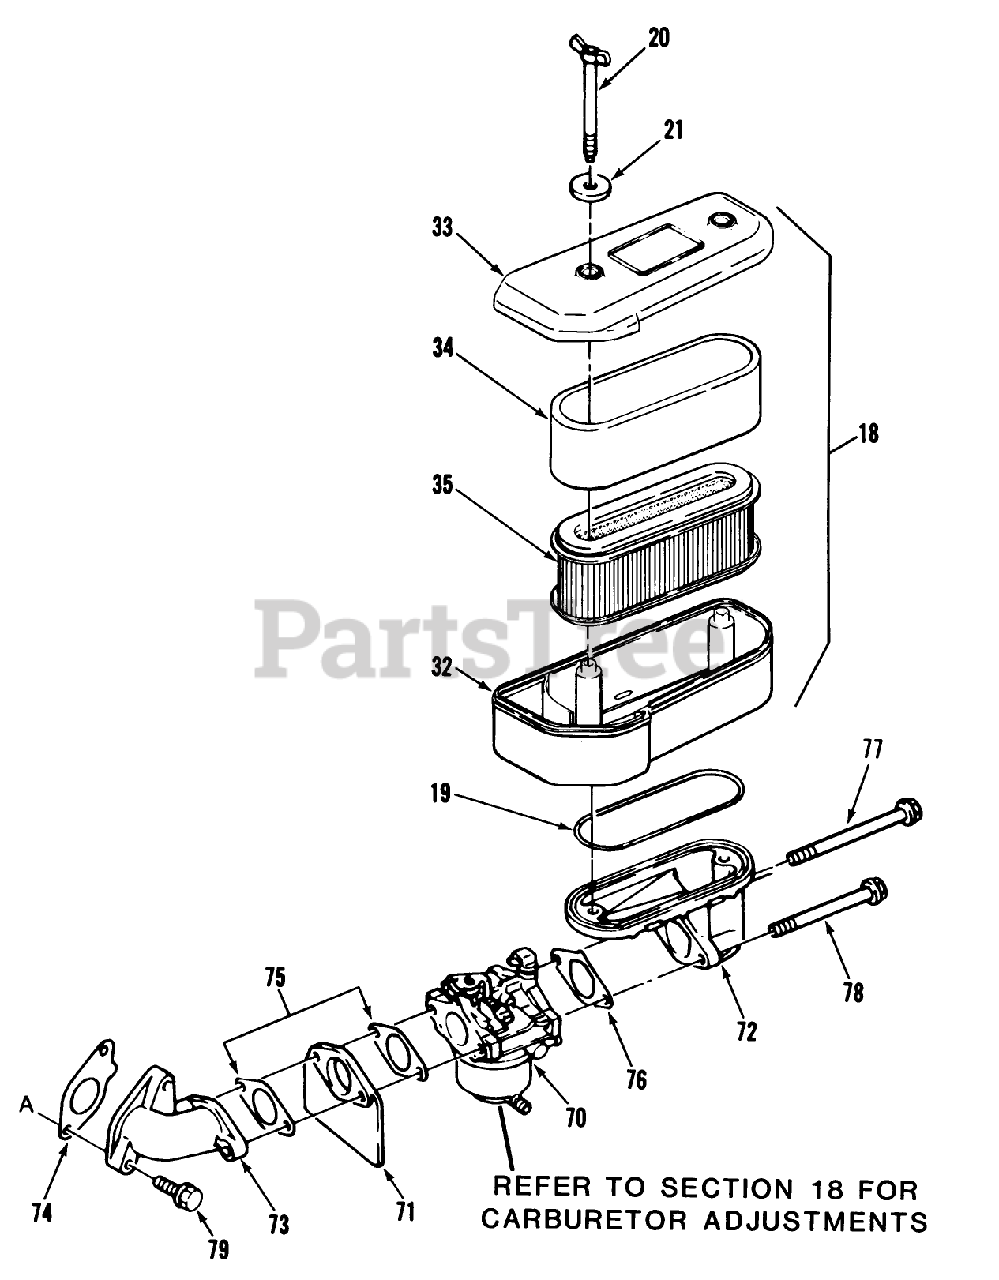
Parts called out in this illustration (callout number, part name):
18	AIR FILTER ASSY
34	ELEMENT-AIR CLEANER
73	MANIFOLD INTAKE
74	GASKET
